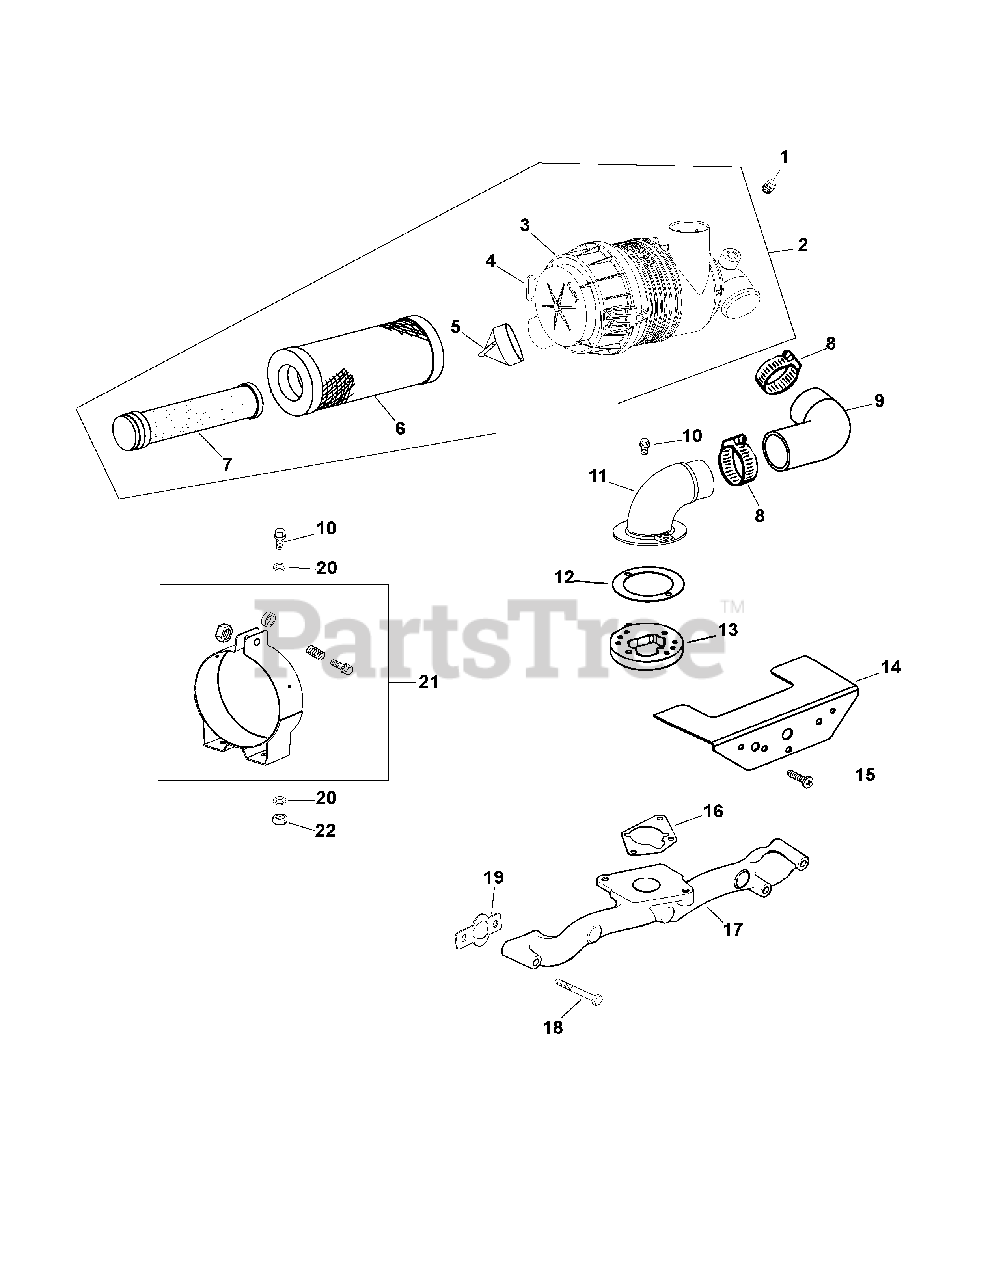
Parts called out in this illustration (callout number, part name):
2	Air cleaner assembly 5-1/4" (Includes 3-8)
3	Cover assembly, plastic air cleaner (Includes 4)
4	Clip
5	Valve, dust ejector
6	Element, air cleaner - primary
7	Element, safety
8	Clamp, hose (2)
9	Hose, air cleaner
10	Adapter, remote air cleaner
11	Screw, hex flange M6x1.0x16 (6)
12	Gasket, adapter
13	Adapter assembly
14	Shield, debris
15	Screw, phillips hd. 11-16x3/4" (2)
16	Gasket, air cleaner base
17	Manifold, intake
18	Screw, hex. flange M6x1.0x55 (4)
19	Gasket, intake manifold (2)
20	Washer, plain (4)
21	Bracket, air cleaner
22	Nut, hex. lock (2)
